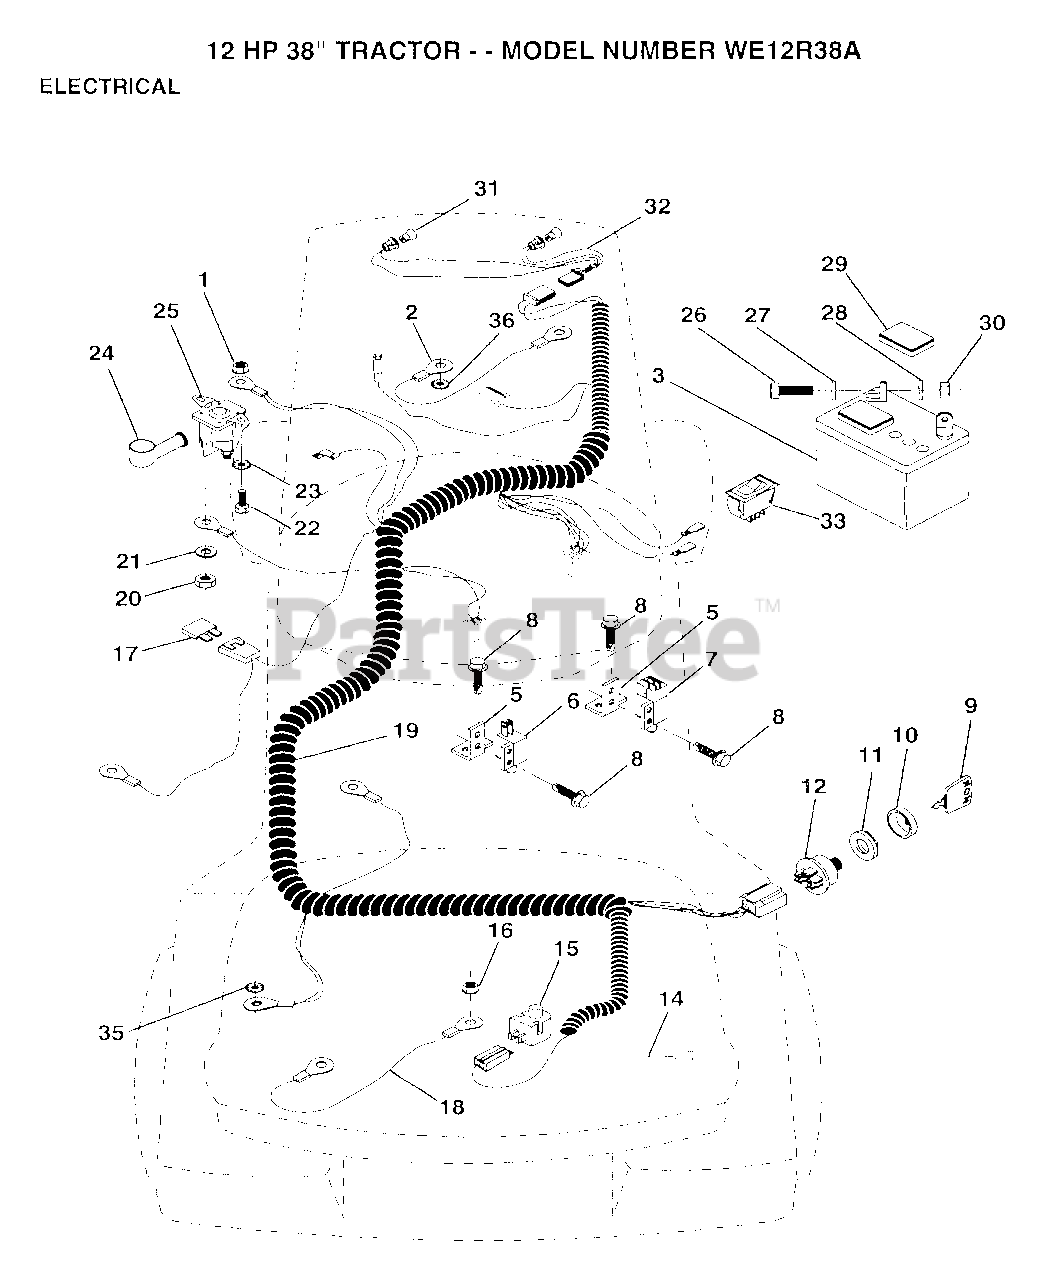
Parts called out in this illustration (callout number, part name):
1	NUT
2	CABLE ASM.
5	BRACKET LT
6	SWITCH-INTER. GT
7	SWITCH INTERLOCKT
8	SCREW
9	KEY
11	NUT IGNITION
14	WIRE TIE
15	SWITCH SEAT
17	FUSE HYT
18	CABLE ASSY
19	HARNESS.IGN
20	NUT
22	BOLT
26	BOLT LT
27	WASHER
28	LOCKWASHER
29	"CAP,BATTERY "
33	SWITCH LT
35	LOCKWASHER
36	LOCKWASHER
